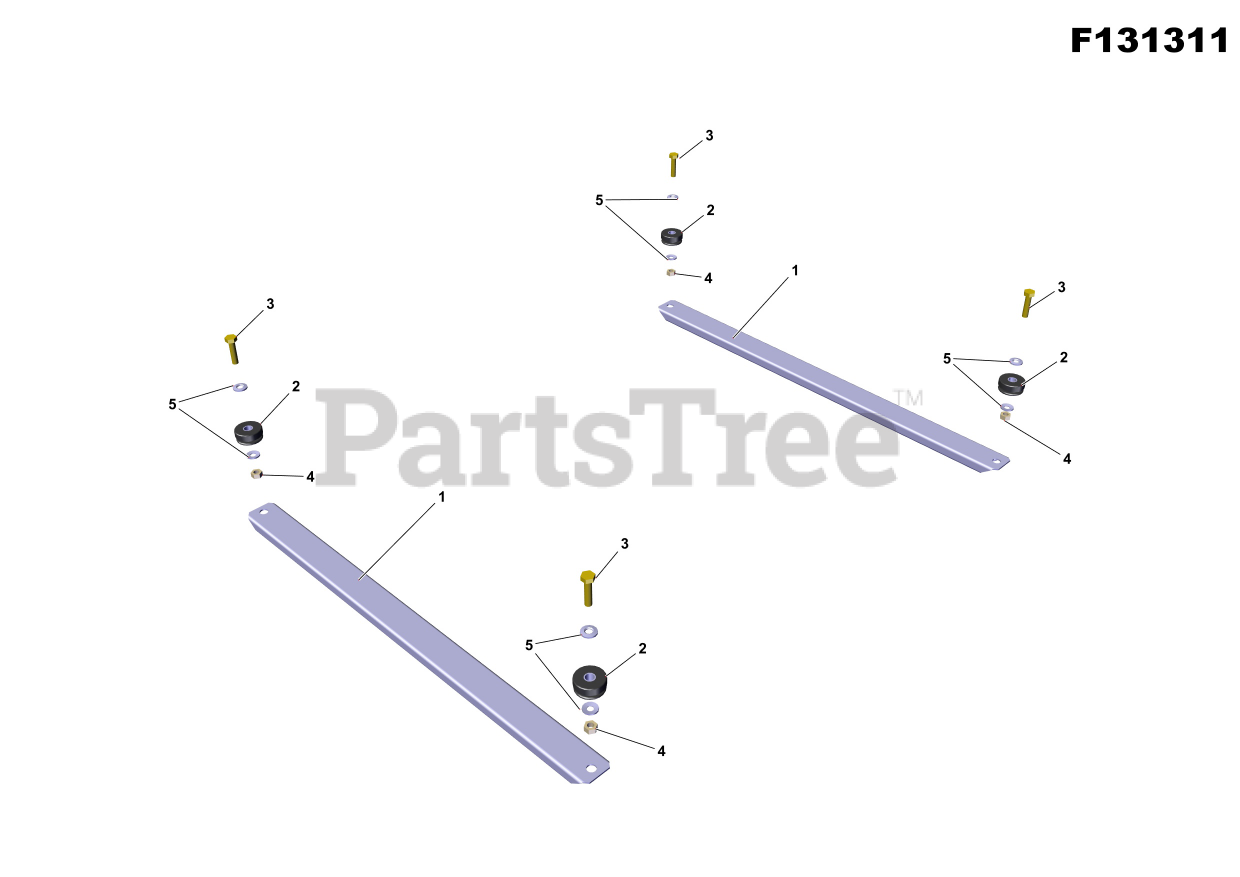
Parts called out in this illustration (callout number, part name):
1	Reinforcement fuel tank
2	Cylindric mount
3	Screw H M6x25
5	Washer CS D6x14
